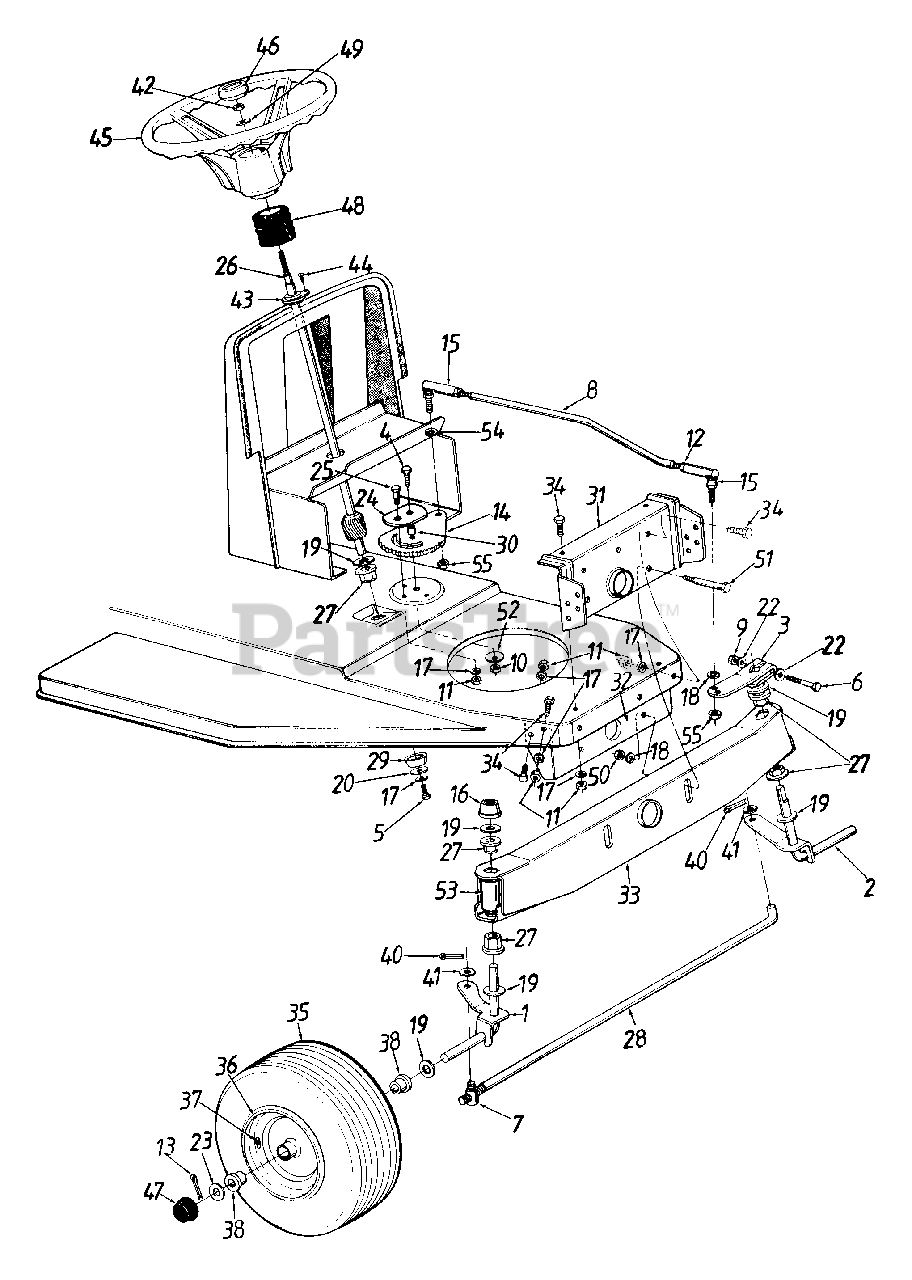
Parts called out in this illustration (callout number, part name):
1	Front Axle Ass'y.- R.H.
2	Front Axle Ass'y.- L.H.
3	Steering Arm
4	Hex Bolt 3/8-24 x 1" Lg.
5	Hex Bolt 5/16-18 x .62"
6	Hex Bolt 5/16-24 x 2" Lg.
7	Ferrule
8	Steering Drag Link
9	Hex L-Nut 5/16-24 Thd.
10	Hex Nut 3/8-24 Thd.
11	Hex Nut 5/16-18 Thd.
12	Hex Jam Nut 3/8-24 Thd.
13	Cotter Pin 1/8" Dia.
14	Steering Gear Segment
15	Drag Link Ball Joint 3/8-24 Thd.
16	Push Cap
17	L-Wash. 5/16" I.D.
18	L-Wash. 3/8" I.D.
19	Fl-Wash..64" I.D. x 1.24"
20	Fl-Wash..340" I.D. x 1.125"
22	Spr. Wash..32" I.D. x .62"
23	Fl-Wash..635" I.D. x 1.585"
24	Retainer Plate
25	Shld. Bolt .437" Dia. x .350"
26	Steering Shaft
27	Hex Flange Brg..634" Dia.
28	Tie Rod 19.1" Lg.
29	Spacer .985" I.D.
30	Spacer .380" I.D.
31	Front Pivot Bar Support Brkt.
32	Rear Pivot Bar Support Brkt.
33	Pivot Bar Ass'y.
34	Hex Bolt 5/16-18 x .62" Lg.
35	Front Wheel Ass'y. Comp. 13" x 6"
37	Air Valve
38	Flange Bearing .632" I.D.
40	Cotter Pin 3/32" Dia.
41	Fl-Wash..406" I.D. x .75"
42	Hex L-Nut 5/16-24 Thd.
43	Steering Column Brg.
44	Cr-Sunk Scr. #10 x 5/8" Lg.
45	Steering Wheel
46	Steering Wheel Cap
47	Hub Cap
48	Bellow Steering Column
49	Bell-Wash..345" I.D. x .88"
50	Hex Nut 3/8-16 Thd.
51	Shld. Bolt 1/2" Dia. x 2.32"
52	Bell-Wash..39" I.D. x 1.4" O.D.
53	Plastic Tube
54	L-Wash. 3/8" I.D. (H.D.)
55	Hex Jam L-Nut 3/8-24 Thd.
